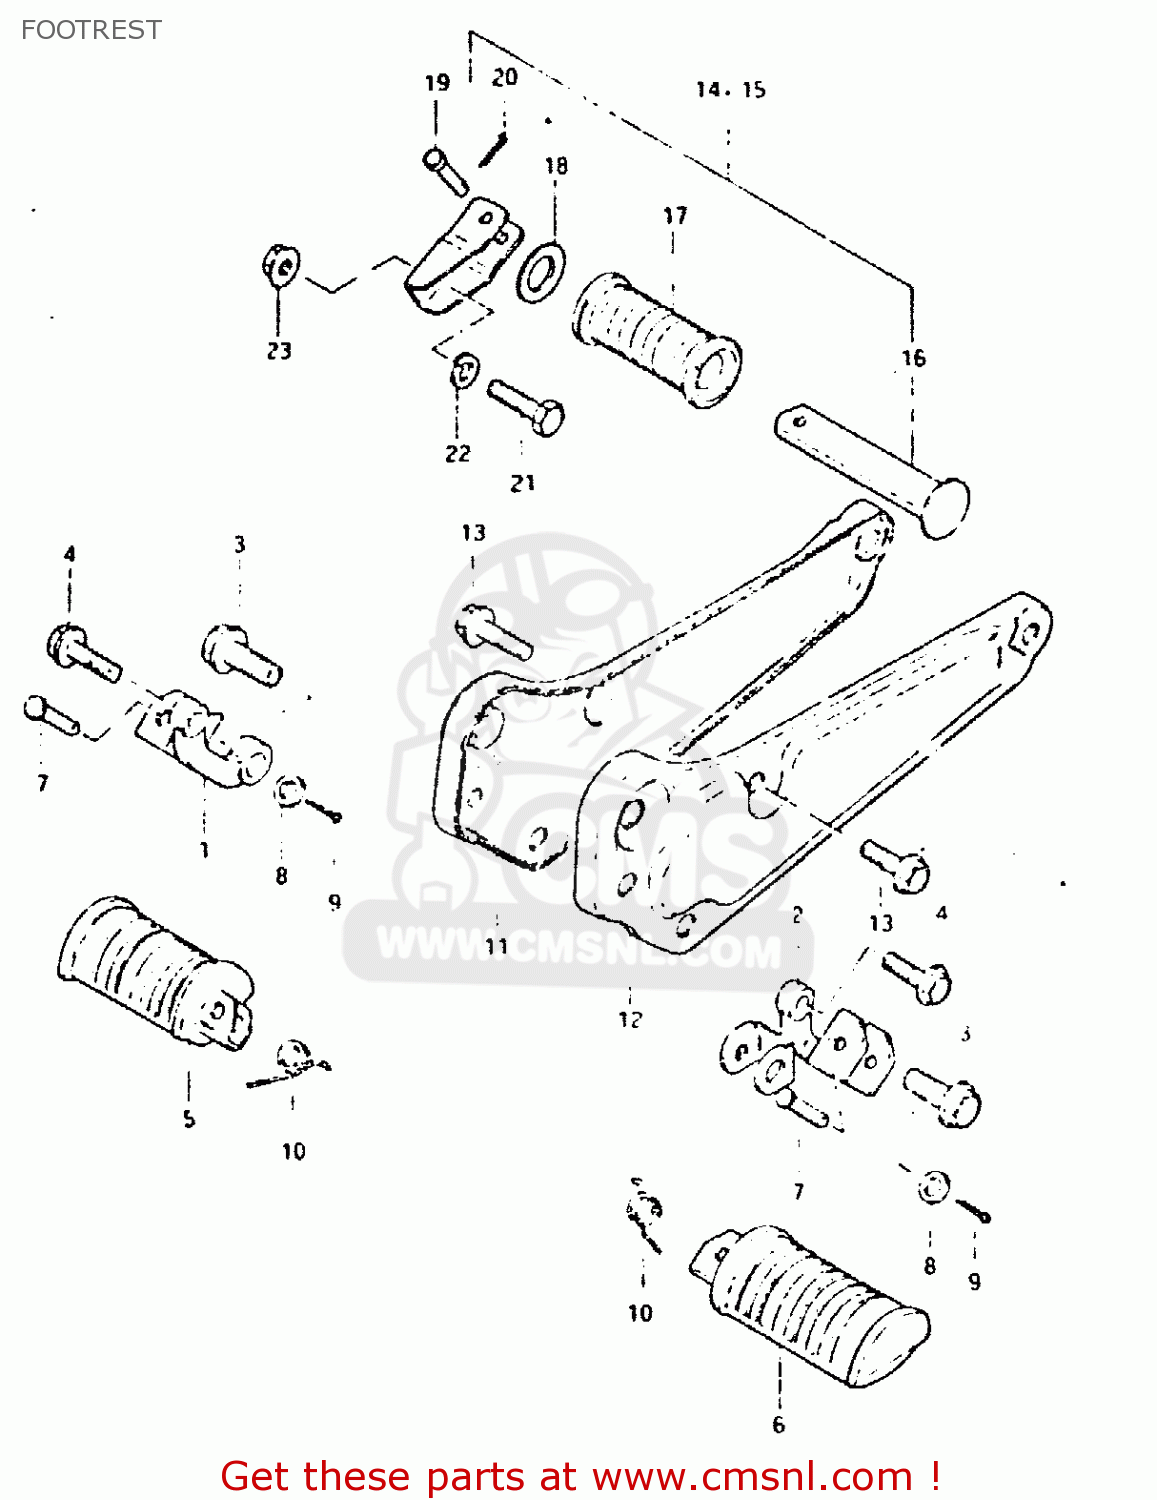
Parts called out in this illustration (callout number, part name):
1	BAR,FRONT FOOTREST,RIGHT
2	BAR,FRONT FOOTREST,LEFT
3	BOLT
4	BOLT
5	RUBBER,FRONT FOOTREST
6	FOOTREST
7	PIN
8	WASHER
9	PIN
10	SPRING
11	BRACKET
12	BRACKET
13	BOLT
14	FOOTREST ASSEMBLY,REAR,RIGHT
15	FOOTREST ASSEMBLY,REAR,LEFT
16	BAR,PILLION FOOTREST
17	RUBBER,PILLION FOOTREST
18	WASHER (19.5X32X2)
19	PIN
20	PIN
21	BOLT,M10X1.25X
22	LOCK WASHER
23	NUT
